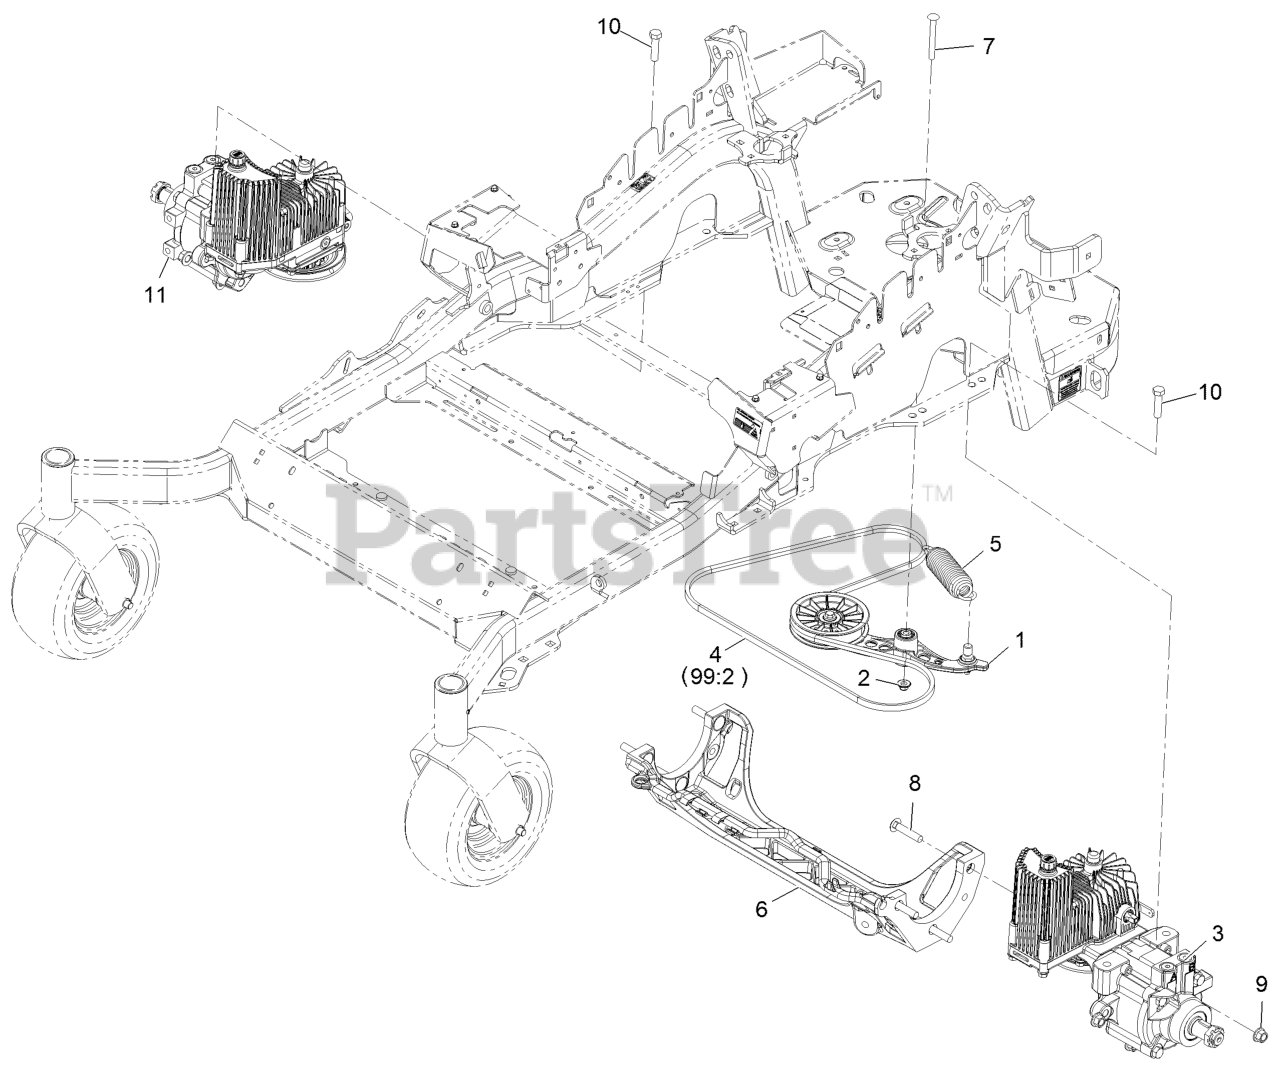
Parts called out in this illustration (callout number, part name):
1	PUMP IDLER ASM
2	Nut-Nyloc 3/8-16 Flg
4	BELT-V
5	SPRING-EXTENSION
7	BOLT-SHOULDER, CARRIAGE 3/8-16 X 3 1/2
8	SCREW-CARR
9	Nut-Lock 1/2-13
10	SCREW-HH
99:2	BELT-V
